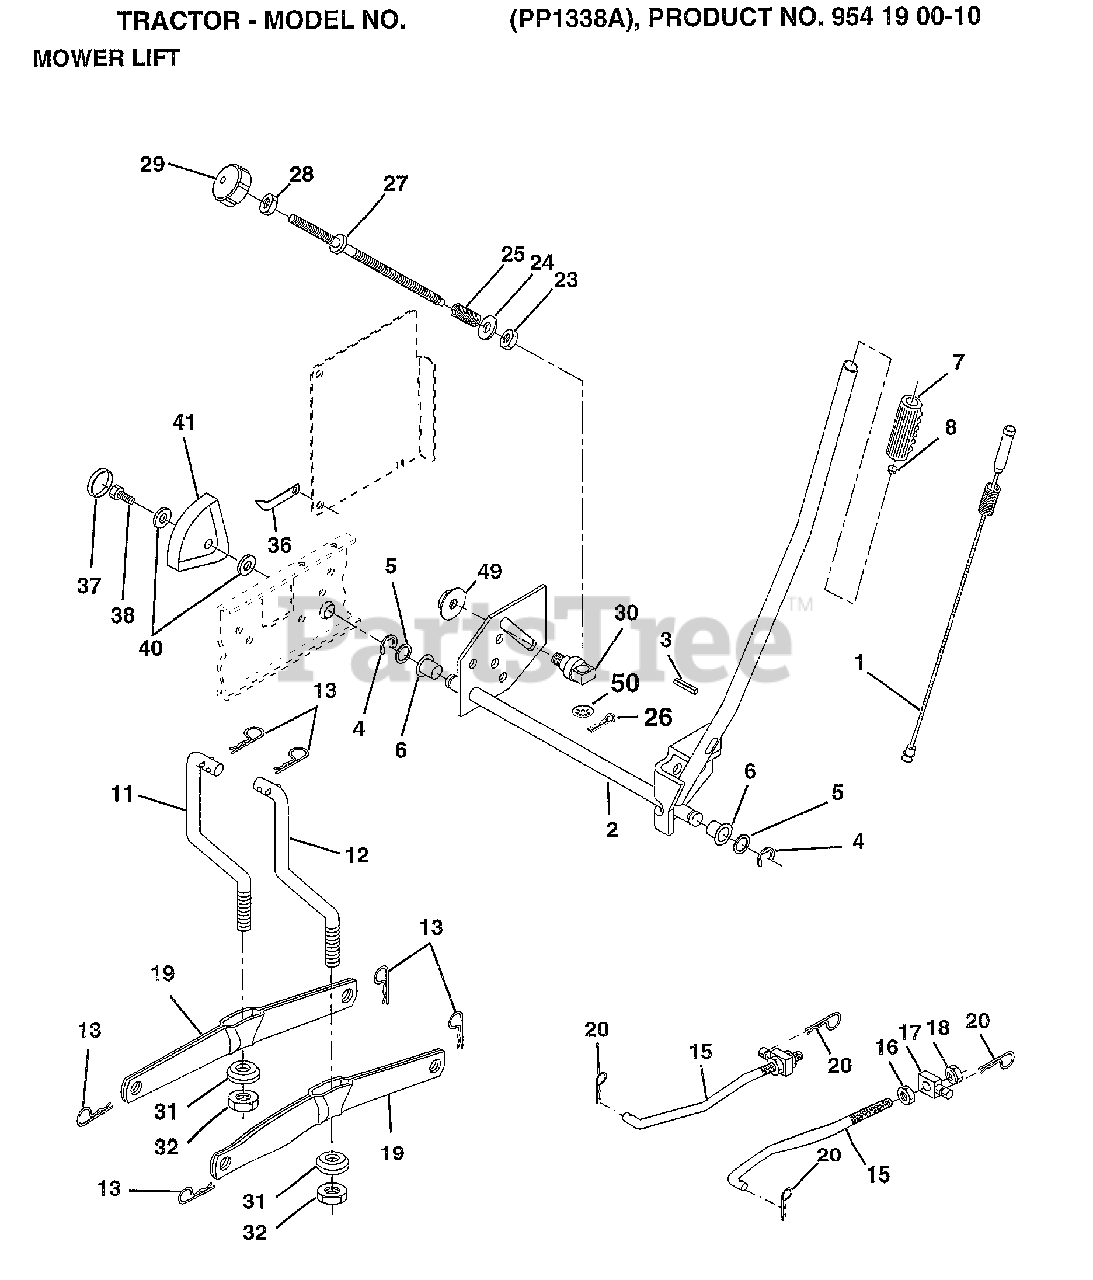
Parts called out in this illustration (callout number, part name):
1	WIRE ASM W.SPRING
2	"SHAFT ASM LIFT,RH"
3	PIN-GROOVE LT
5	WASHER
6	NYLON BEARING
7	GRIP
15	LINK.FRONT
16	NUT
17	TRUNION
18	NUT.LK.W/WSH.1/2.
19	ARM SUSP REAR
20	RETAINER.SPRING
23	NUT T
24	WASHER
25	SPRING T
28	NUT
29	KNOB INF 3/8-16
30	TRUNNION
31	BEARING PVT LH
32	NUT.CROWNLOCK.3/8
36	POINTER-INDICAT
37	"PLUG,HOLE"
38	SCREW
40	WASHER
41	HEIGHT INDICATOR
49	NUT.HXFLG.LOCK.
50	NUT PUSH M
